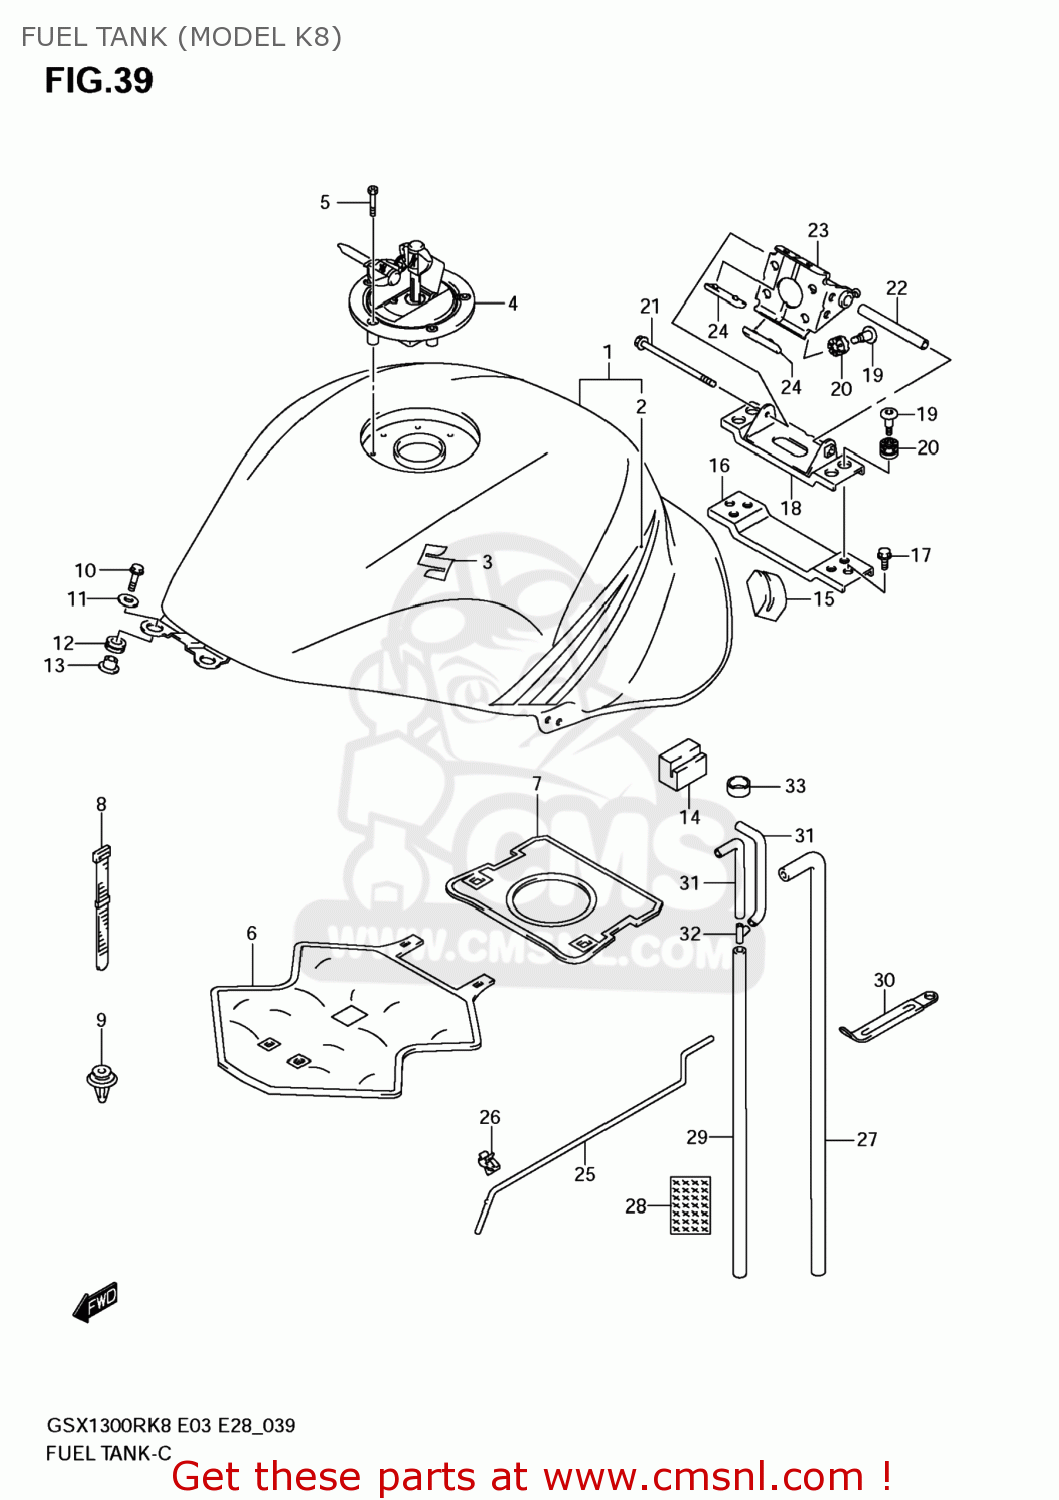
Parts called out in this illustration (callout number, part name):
1	TANK ASSY,FUEL
2	TAPE SET,FUEL TANK
3	EMBLEM,S
4	CAP SET,FUEL TANK
5	BOLT(5X20)
6	SHIELD,FUEL TANK HEAT NO.1
7	SHIELD,FUEL TANK HEAT NO.2
8	CLAMP(L:165)
9	CLIP
10	SCREW(6X25)
11	WASHER(6.5X22X1.6)
12	CUSHION,FUEL TANK FR
13	SPACER,FUEL TANK FR
14	CUSHION,FUEL TANK SIDE
15	CUSHION,FUEL TANK RR
16	BRACKET,FUEL TANK RR NO.3
17	BOLT
18	BRACKET,FUEL TANK RR NO.2
19	SCREW,FUEL TAN
20	CUSHION
21	BOLT
22	SPACER,FUEL TANK RR
23	STEUN.BENZ.TANK
24	CUSHION,SEAT FR
25	STAY,FUEL TANK
26	CLAMP
27	HOSE,FUEL TANK DRAIN
28	SHIELD,DRAIN HOSE HEAT
29	HOSE,FUEL TANK BREATHER
30	CLAMP(L:65)
31	HOSE,TANK BREATHER NO.2
32	3 WAY
33	HOSE(12X16X600)
